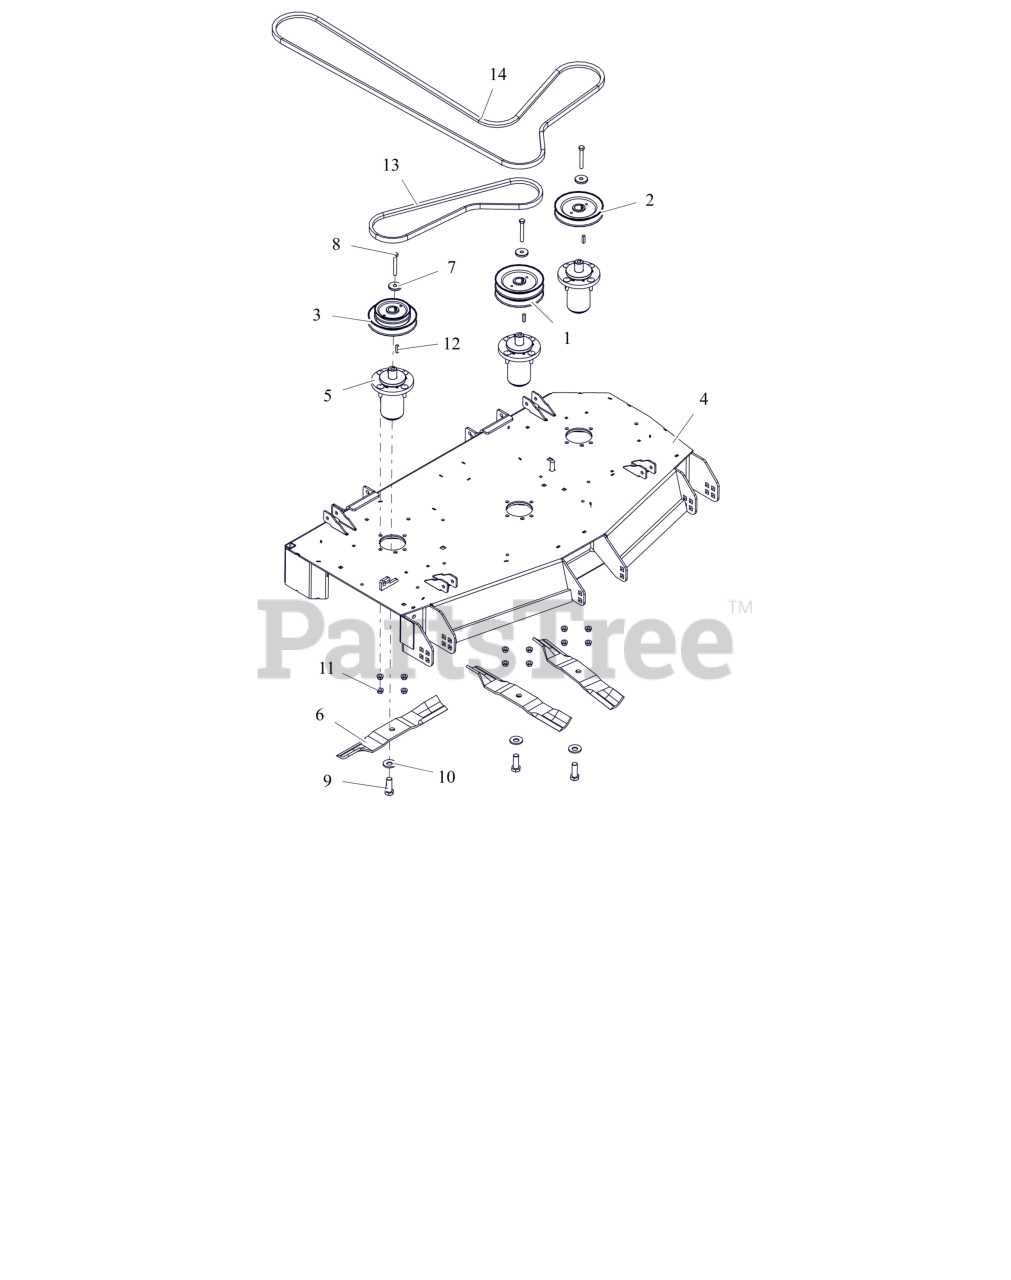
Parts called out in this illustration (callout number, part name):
1	PULLEY, DOUBLE-1"ID X 5.75"OD
2	PULLEY, V-1" ID X 5.75" OD
3	PULLEY, DBL-1"IDX5.75"&4.25"OD
4	WLDMT- 48" SIDE DISCH DECK
5	ASM, MAINT FREE ALUM SPINDLE
6	BLADE, 16.19" MOWER (HI-LIFT)
7	RETAINER, SHEAVE
8	BLT, HEX .38-16X2.75 G8 ZCC
9	BLT, HEX .62-18X1.75 G8 ZCC
10	WSHR-BLVL .669X1.535X.138
11	NUT-LK-CTR-FLG .375-16 GF ZCC
12	KEY, SQ .25X.25X1.00 RC 40-50
13	V-BELT, B-COGGED
14	V-BELT, HB RAW EDGE EPDM
